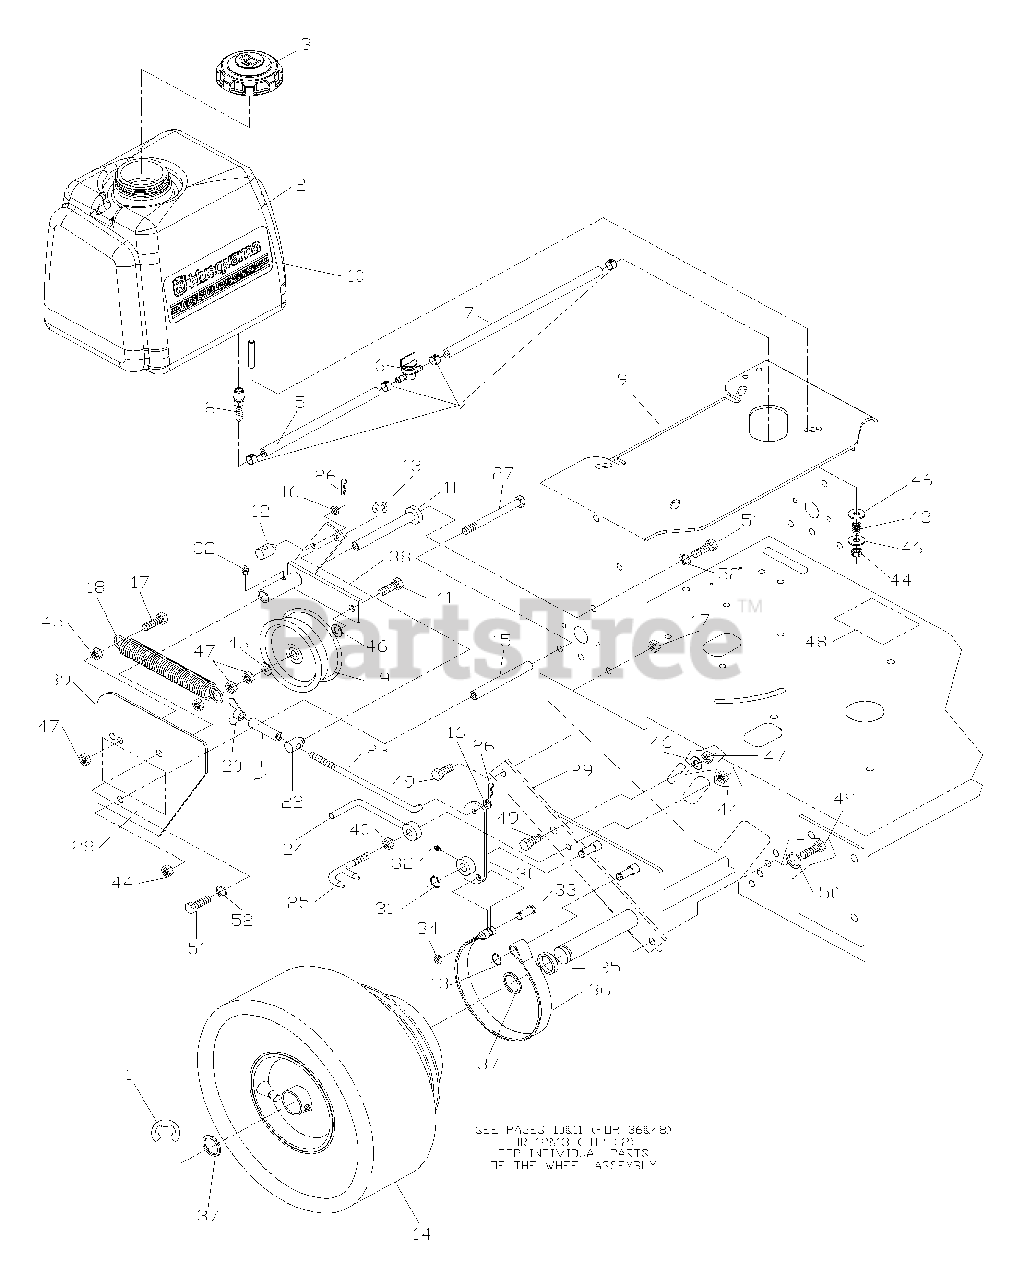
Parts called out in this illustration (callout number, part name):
1	1" E-RING
3	GAS CAP
4	HOSE CLAMP
5	10" GAS LINE
6	FUEL VALVE
7	14" GAS LINE
9	REAR DECK W/DCLS
10	DECAL
11	PIVOT TUBE
12	SWIVEL (SHORT)
13	3/8" E-RING
14	WHEEL ASM.
15	LONG SPACER
16	5/16 FW STD
17	HCS 3/8C X 1 1/4
19	IDLER PULLEY
20	5/16 WINGNUT
24	BELT GUIDE
25	SCRAPER
26	#2 HAIRPIN
27	HCS 5/16C X 5
28	DECAL, CROWN
29	AXLE WLDMT
30	RT. BRAKE ARM
30	LT. BRAKE ARM
31	1/2' E-RING
32	ZERK 1/4-28 STRHT
33	CLEVIS PIN
34	BOLT RETAINER 3/8
36	BRAKE BAND
37	MACH. BUSHING
38	IDLER PLATE, RT
38	IDLER PLATE, LT
40	HFLN 5/16C
41	3/8C X 3 TAPBOLT
46	FW 3/8 STD
47	HLN 3/8C CENTER P.
48	DECAL, PROP. 65
49	HCS 3/8C X 1
50	SLW 3/8 STD
51	HCS 5/16C X 1
52	SLW 5/16 STD
